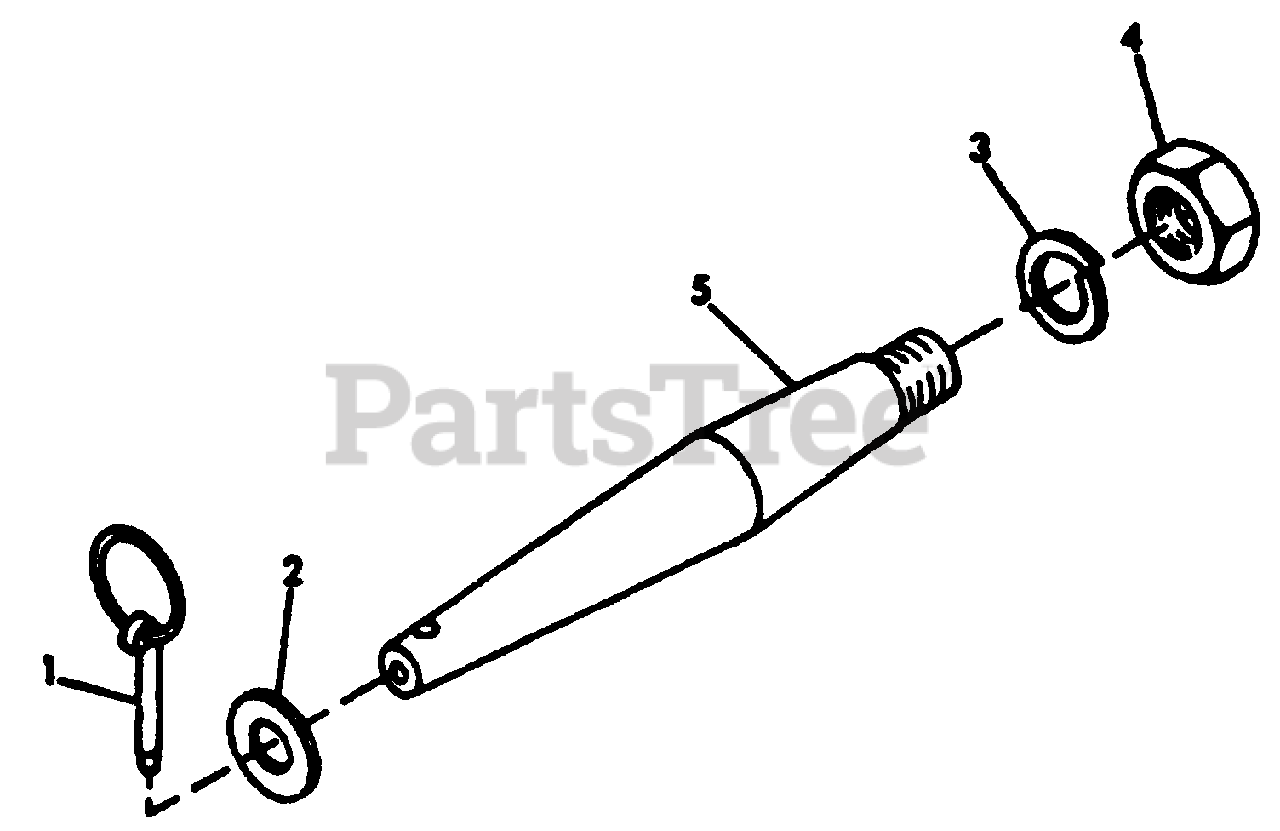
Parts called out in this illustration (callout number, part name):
1	PIN, KLIK
2	WASHER, FLAT .656 X 1.312 X .095
3	WASHER, LOCK 3/4 SP
4	NUT, JAM 3/4-10 HEX HEAVY
5	PIN, QUICK HITCH
